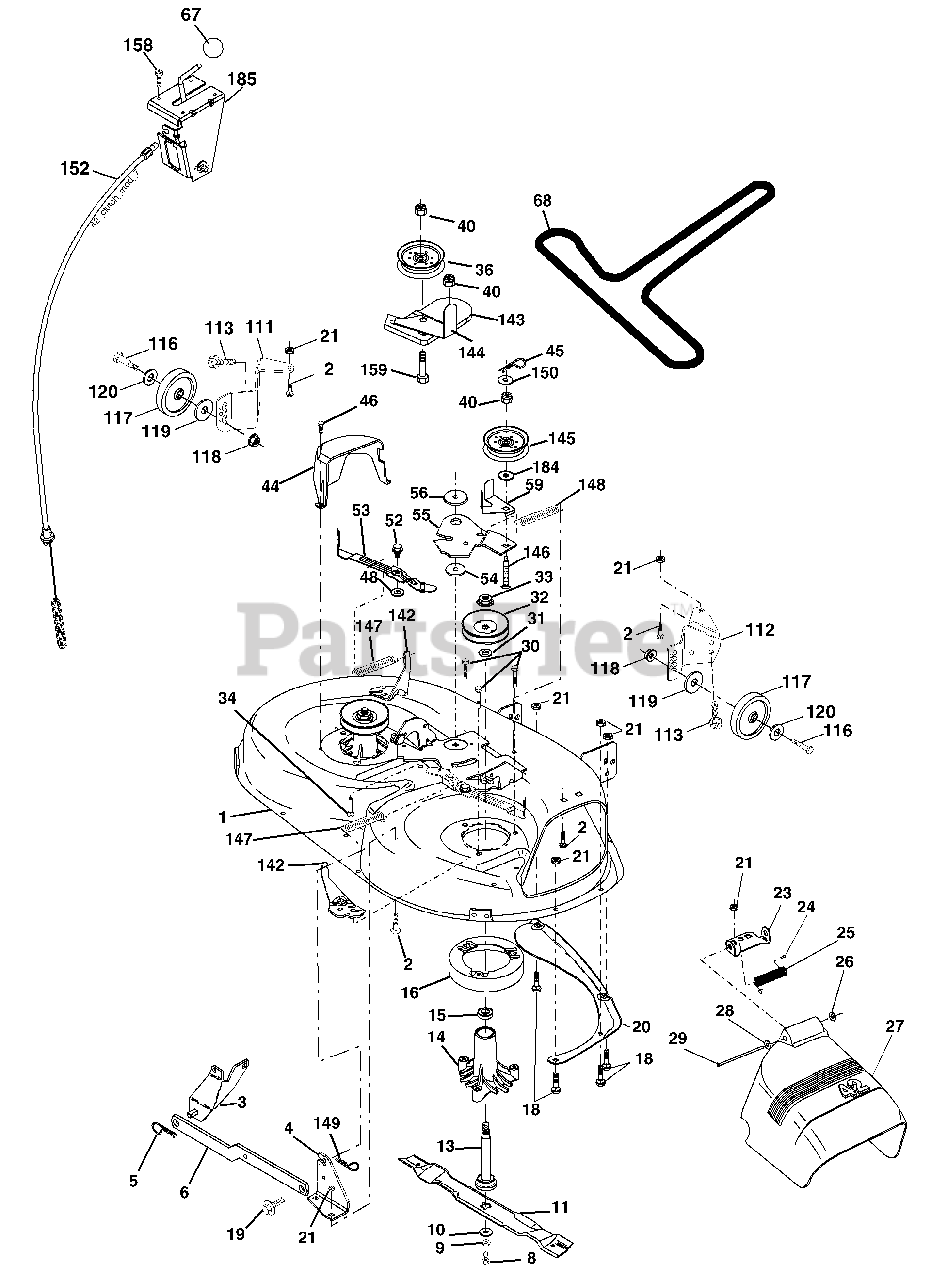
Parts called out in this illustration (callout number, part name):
1	Mower Deck Assembly, 42"
2	Bolt
3	Bracket Asm Fr. Sway Bar 3/42
4	Bracket Asm Deck 42" Sway Bar
5	Retainer Spring
6	Bar Sway Deck
8	Bolt 3/8-24 x 25 Gr. 8 patched
9	Washer, Lock
10	Washer, Hardened
11	Blade, 42" Mulching Std
11	Blade, 42" Mulching Premium
11	Blade, 42" Hi-Lift
13	Shaft Assembly, Mandrel, Vented
14	Housing, Mandrel, Vented
15	Bearing, Ball, Mandrel
16	Stripper, Mandrel Deck
18	Bolt, Carriage 5/16-18 x 5/8
19	Bolt, Shoulder
20	Baffle, Vortex
21	Nut
23	Bracket, Deflector Mower 42"
24	Cap, Sleeve 80 x 112 Blk Mower
25	Spring, Torsion, Deflector 2 52
26	Nut, Push Phos & Oil
27	Shield, Deflector 42" Blk
28	Washer 11/32 x 5/8 x 16 Ga.
29	Rod, Hinge 42" 6 75 W/G
30	Screw Thdrol Washer Head
31	Washer, Spacer Mower Vented
32	Pulley, Mandrel
33	Nut, Toplock 9/16 Flange
34	Bolt
36	Pulley, Idler, Flat
37	Washer 13/32 x 13/16 x 16 Ga.
44	Guard, Mandrel, LH
45	Retainer
46	Screw, Thdrol 1/4-20 x 5/8 T
48	Washer, Hardened
52	Bolt, Shoulder 5/16-18 unc
53	Arm Assembly, Pad, Brake
54	Washer, Hardened
55	Arm, Idler
56	Spacer, Retainer
59	Guard TUV Idler
67	Knob
68	V-Belt, 42" Mower
111	Bracket Wheel Gauge LH
112	Bracket Wheel Gauge RH
113	Bolt 5/16-18
116	Bolt Shoulder
117	Wheel Gauge
118	Nut Centerlock 3/8-16
119	Washer 3/8 x 7/8 x 14 Ga.
120	Washer 17/32 x 15/16 x 12 Ga.
142	Arm Spring Brake Mower
143	Bracket Arm Idler 42"
144	Keeper Belt 42" Clutch Cable
145	Pulley Idler Flat
146	Bolt Carriage Idler
147	Spring Extension
148	Spring Return Idler
149	Retainer Spring Yellow
150	Washer 9/32 x 3/4 x 10 Ga.
152	Clutch Cable 42"
158	Screw Hex Thd Cut 1/4-20 x 1/2
159	Bolt Rdhd Sqn 3/8-16 unc x 1-3/4
184	Washer 13/32 x 7/8 x 10 Ga.
185	Head Asm Cable Clutch
